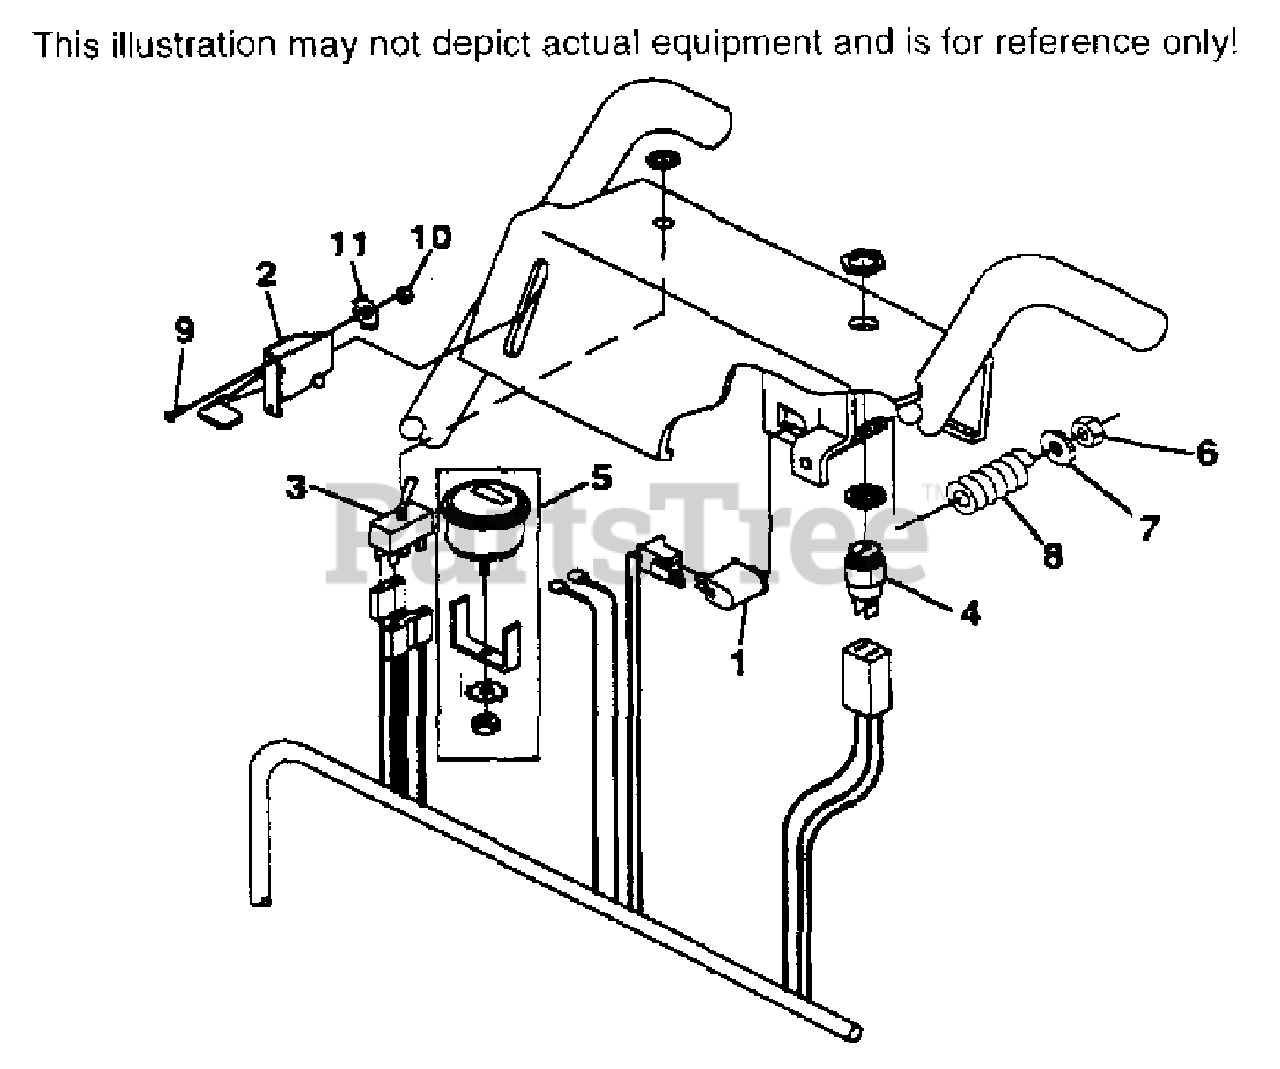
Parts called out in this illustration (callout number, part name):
1	SWITCH, NEUTRAL INTERLOCK
2	THROTTLE CONTROL
3	ENGAGEMENT SWITCH, ELECTRIC CLUTCH(INCLUDES
5	HOUR METER(DEALER INSTALLED)
6	NUT, 5/16-18 ELASTIC STOP NUT
8	SPRING, OPERATOR PRESENCE
9	SCREW, #10-32 X .50 PHILLIPS WASHER HEAD
10	NUT, #10-32 SERRATED FLANGE HEX HEAD
11	LOCKWASHER, #10 EXTERNAL TOOTH
NS	CLAMP, WIRE HARNESS
